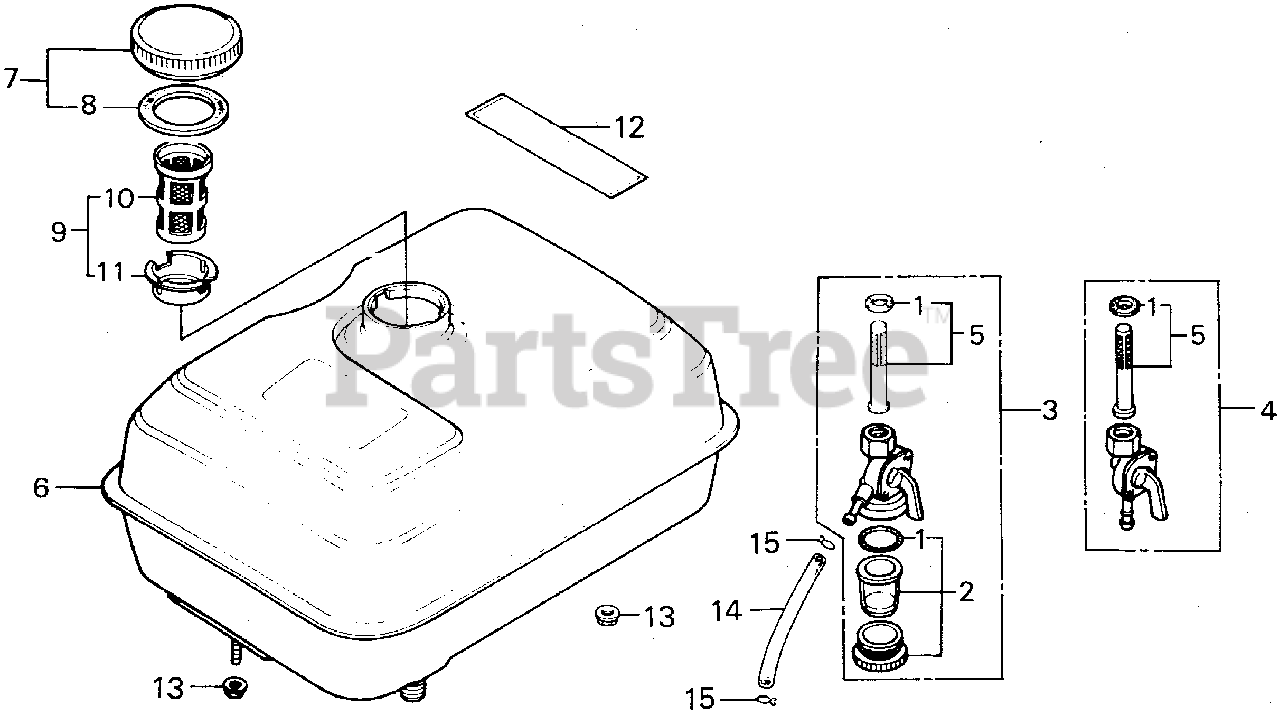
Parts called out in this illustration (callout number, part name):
4	PETCOCK ASSY.
5	SCREEN SET
6	TANK, FUEL *NH31* (MCKINLEY WHITE)
7	CAP, FUEL FILLER
8	GASKET, FUEL FILLER CAP
9	FILTER, FUEL Use up to Engine SN 1370794.
10	FILTER, FUEL Use from Engine SN 1370795.
10	FILTER, FUEL Use up to Engine SN 1370794.
11	HOLDER, FUEL FILTER Use up to Engine SN 1370794.
11	HOLDER, FUEL FILTER Use from Engine SN 1370795.
12	MARK, CAUTION (ENGLISH/FRENCH)(SPANISH)
13	NUT, FLANGE (6MM)
14	BULK HOSE, FUEL (4.5X3000) (4.5X70)
15	CLIP, TUBE (B8)
